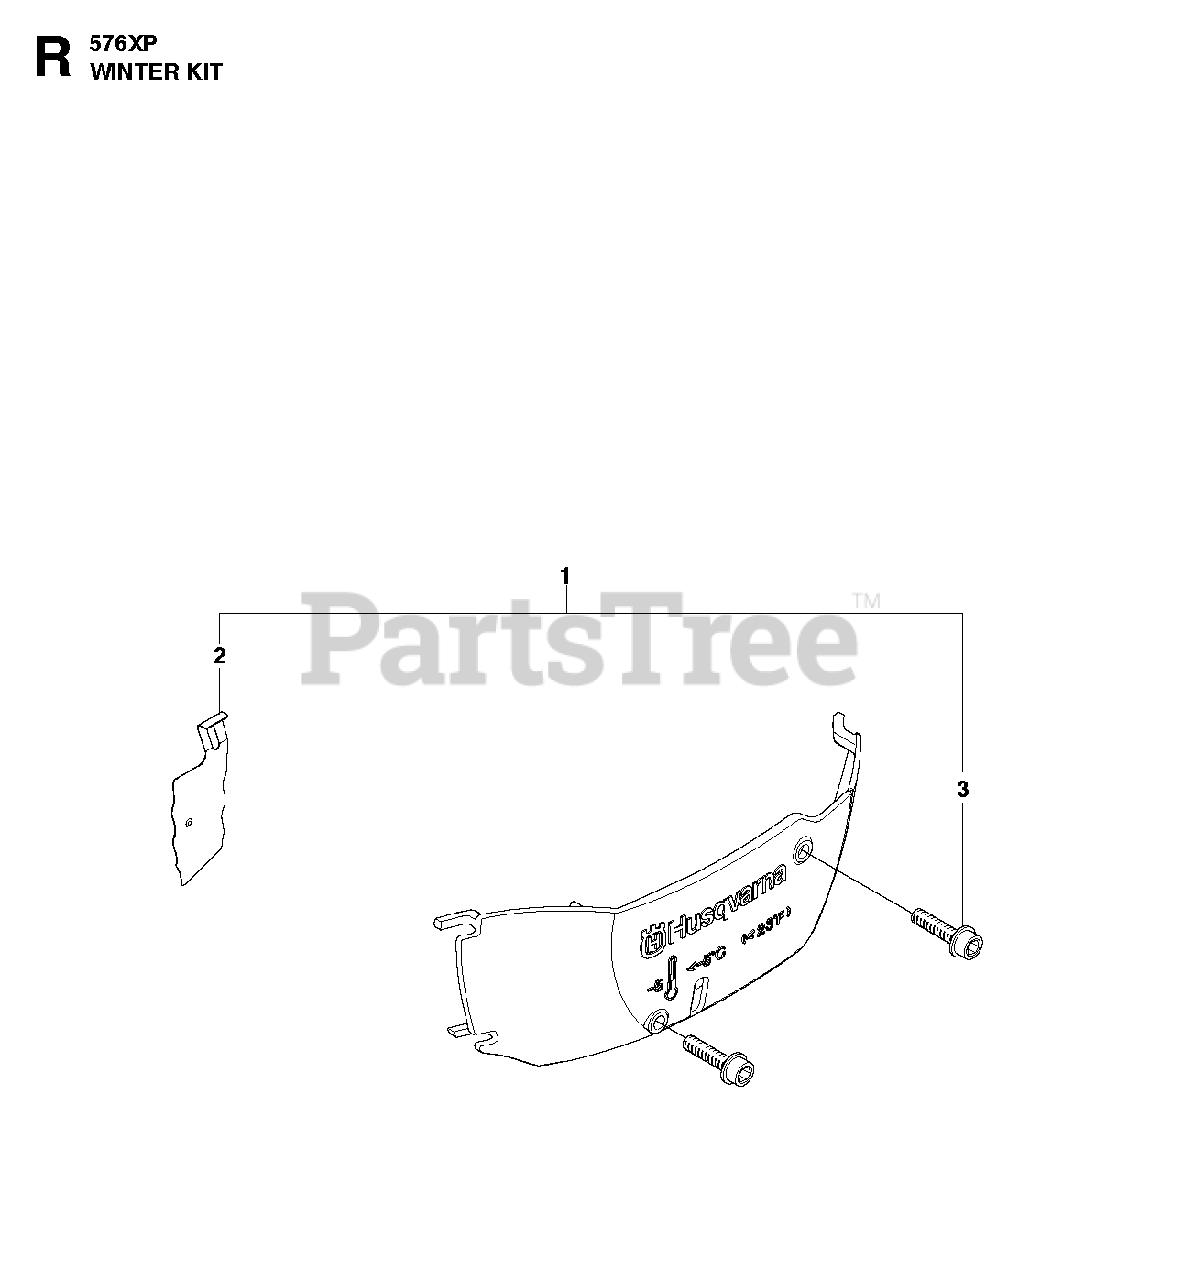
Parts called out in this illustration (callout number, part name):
1	WINTER KIT
2	COVER
3	SCREW
